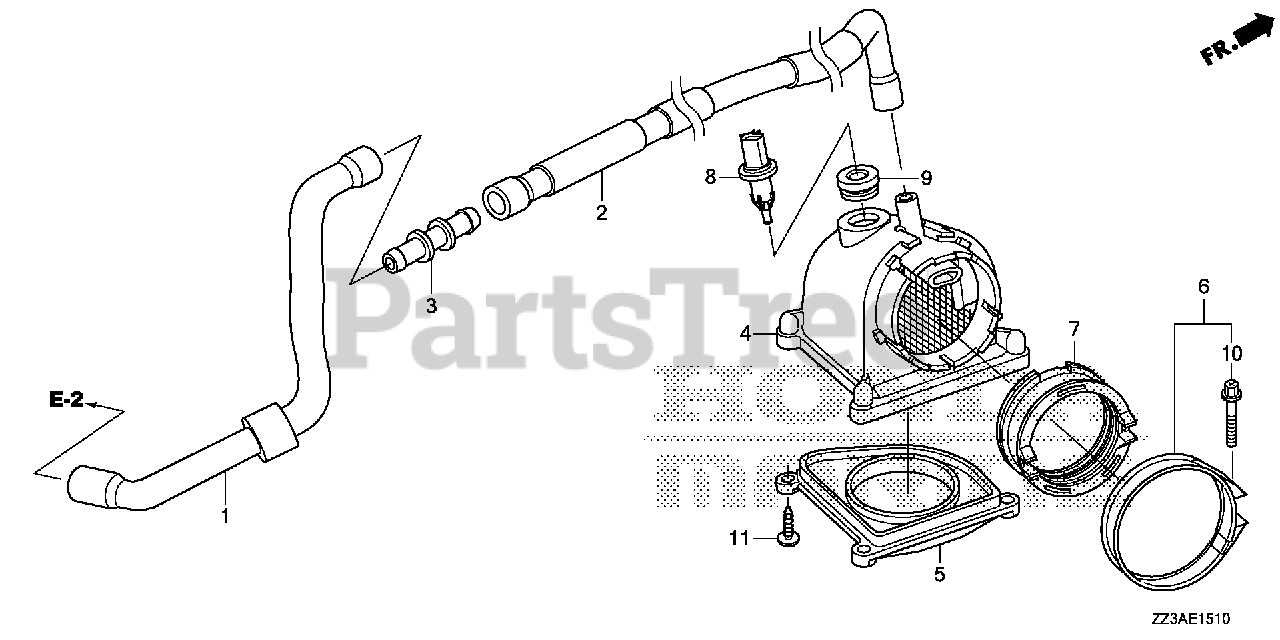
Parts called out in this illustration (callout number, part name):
1	TUBE A, BREATHER
2	TUBE B, BREATHER
3	JOINT, FUEL TUBE
4	GUIDE, AIR
5	PLATE, AIR GUIDE
6	BAND, AIR FLOW
7	GROMMET, AIR GUIDE
8	SENSOR ASSY., AIR TEMPERATURE (MATSUSHITA DENSHI)
9	GROMMET, TA SENSOR
10	BOLT, CLAMP (4X35)
11	SCREW, TAPPING (5X20)
